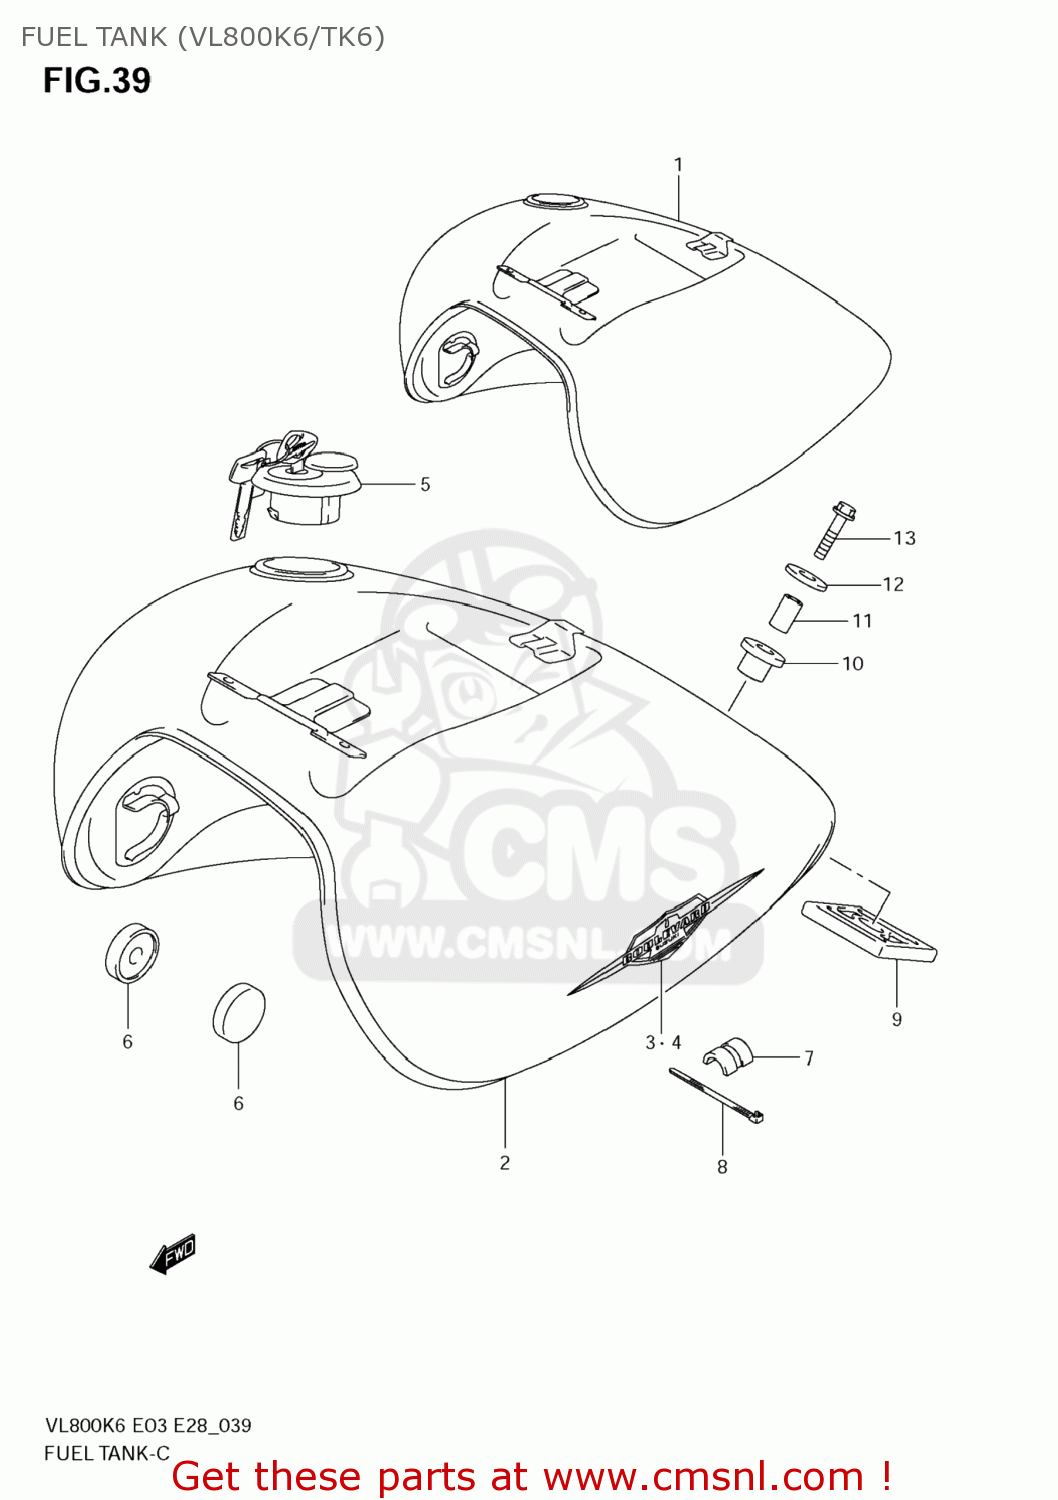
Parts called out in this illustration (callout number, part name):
1	TANK ASSY,FUEL(BLACK)
2	TANK ASSY,FUEL(GRAY)
3	EMBLEM, RH
4	EMBLEM, LH
5	CAP SET,FUEL TANK
6	CUSHION
7	CUSHION,FUEL TANK LWR
8	CLAMP(L:250)
9	CUSHION,FUEL TANK RR LWR
10	CUSHION,FUEL TANK RR UPR
11	SPACER (8.2X12.5X23.5)
12	WASHER (8.5X33X1.6)
13	BOLT
